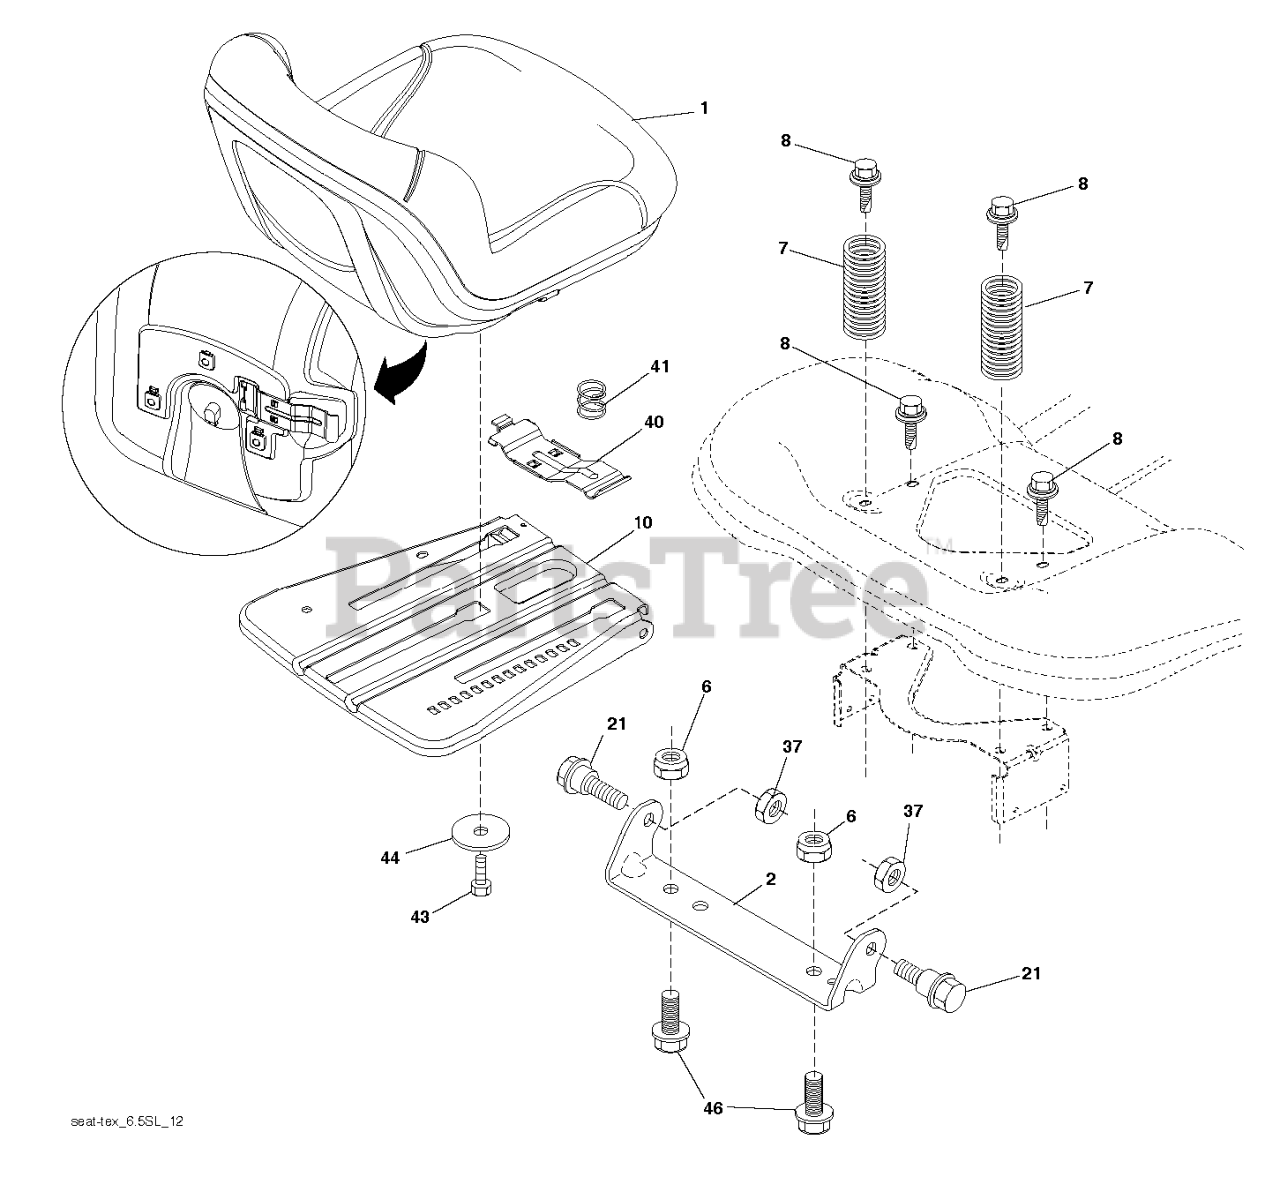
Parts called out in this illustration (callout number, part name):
1	SEAT.TH154.GREY.HUS.ARMREST
2	BRKT.PIVOT.FENDER
6	NUT
7	SPRING.COMPRESSION.SEAT.BLACK
8	BOLT.5/16-18UNCX3/4 W/SEMS.BLK
10	PAN.ASM.SEAT.3PT
21	BOLT.5/16-18X5/8.SHOULDER
37	NUT.71038.31-18.HEX.NYLOCK
40	HANDLE.SLIDE.SEAT.TEX.GREY
41	SPRING.LATCH.SEAT.TEX
44	WASHER 13/32 X 2-3/8 X 12GA
46	BOLT.3/8-16X1;1.25OD.WSHR.SEMS
